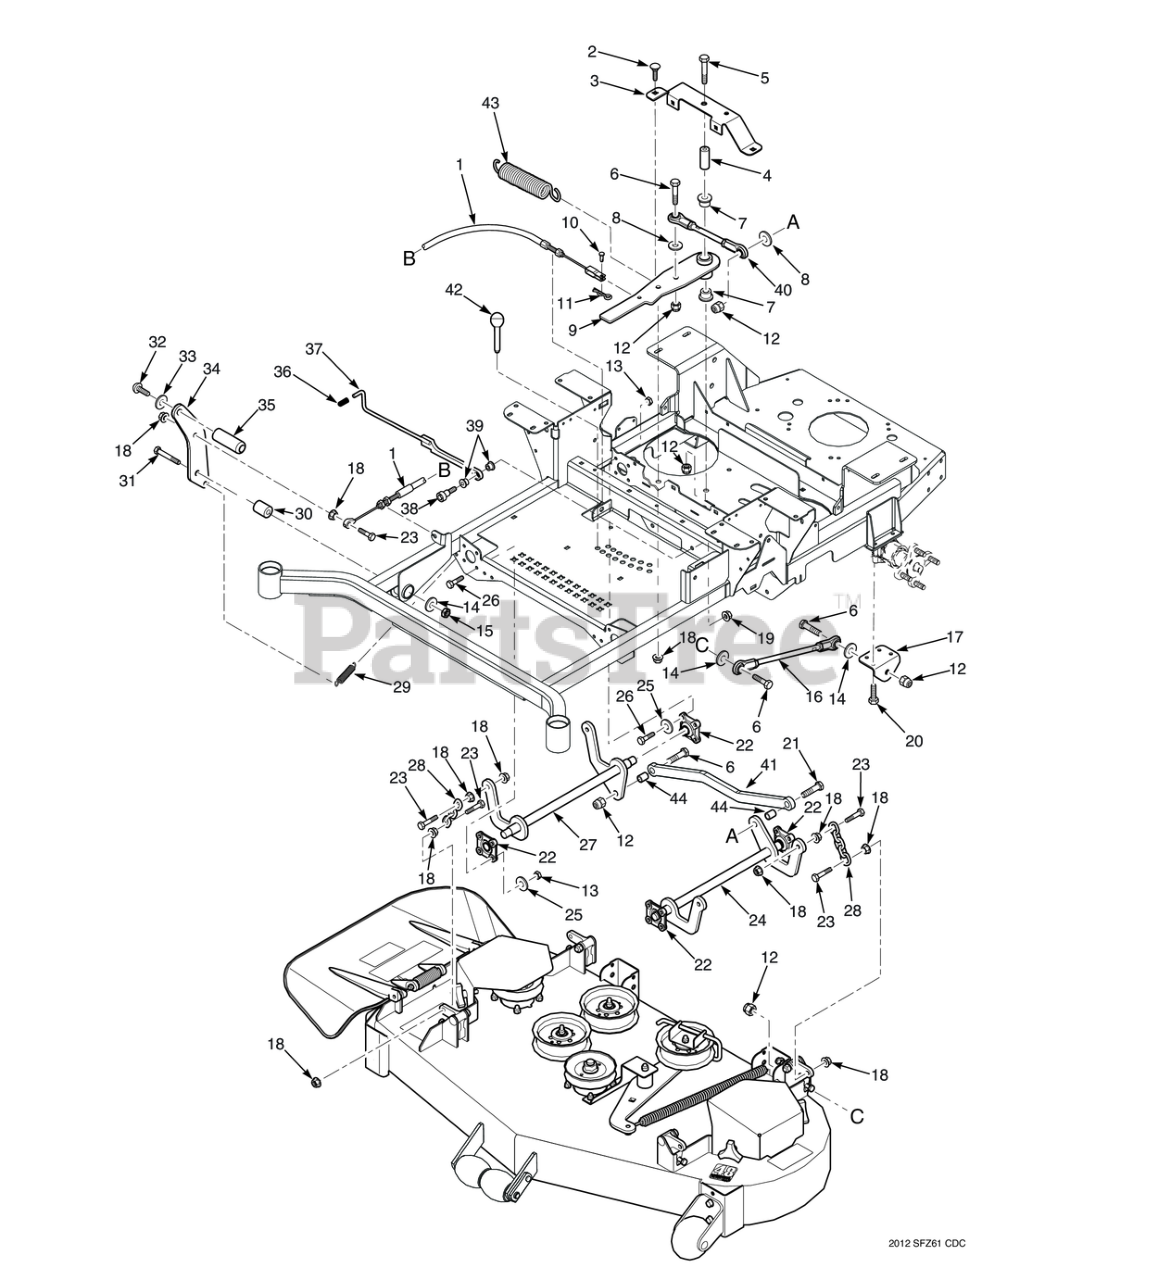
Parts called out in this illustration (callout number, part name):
1	Cable, Deck Lift
2	Bolt, Carriage 3/8-16 x 3/4"
3	Support, Idler Arm
4	Spacer, Deck Lift Pivot
5	Bolt, Hex Head, 1/2-13 x 3-1/4"
6	Hex Head Bolt, 1/2-13 x 2"
7	Bearing, Plastic
8	Flatwasher, 1/2 - .531 x 1.062 x .095
9	DECKLIFT BELLCRANK ASSY, SFZ
10	Clevis Pin, 5/16 x 3/4"
11	COTTER PIN, HAIR - 0.94 X 1.62
12	HEX LOCKNUT, ELASTIC STOP, 1/2-13
13	Nut, Flange Head Elastic Stop 5/16-18
14	Flat Washer, 1/2 (.562 x 1.375 x .109)
15	HEX NUT, ELASTIC STOP LOCK, 3/8-16
16	Linkage, Push Arm
17	Bracket, Push Arm Link
18	NUT, 3/8-16 SERRATED FLANGE HEX HEAD
19	HEX NUT, ELASTIC STOP LOCK, 3/8-16
20	Bolt, Hex Head 5/16-18 x 3.00"
21	Bolt, Hex Head 1/2-13 x 3"
22	Bearing, Deck Lift - 48V & 52V
23	Bolt, Hex Head, 3/8-16 x 1-1/2"
24	Weldment, Deck Lift LH
25	Flatwasher, 1/4" (.312 x .750 x .065")
26	Bolt, Heax Head 5/16-18 x 1" (48V / 52V)
27	Weldment, Deck Lift RH
28	Chain, Deck Lift
29	Spring, Deck Lift
30	Spacer, Deck Lift Pivot
31	Bolt, Hex Head 1/2-13 x 3"
32	Bolt, Head Socket 5/8-11 x 1-1/2"
33	Lockwasher, 5/8" Spring
34	Pedal, Foot Bracket
35	Foot Pedal, Height Adjustment
36	Grip, Deck Latch
37	Weldment, Deck Latch
38	Bolt, Shoulder 1/2 x 1/2"
39	Bearing
40	Linkage Assembly, Deck Lift
41	Mounting Bracket, Fuel Tank Front
42	Pin, Height Adjuster
43	Spring, Deck Lift
44	Sleeve
